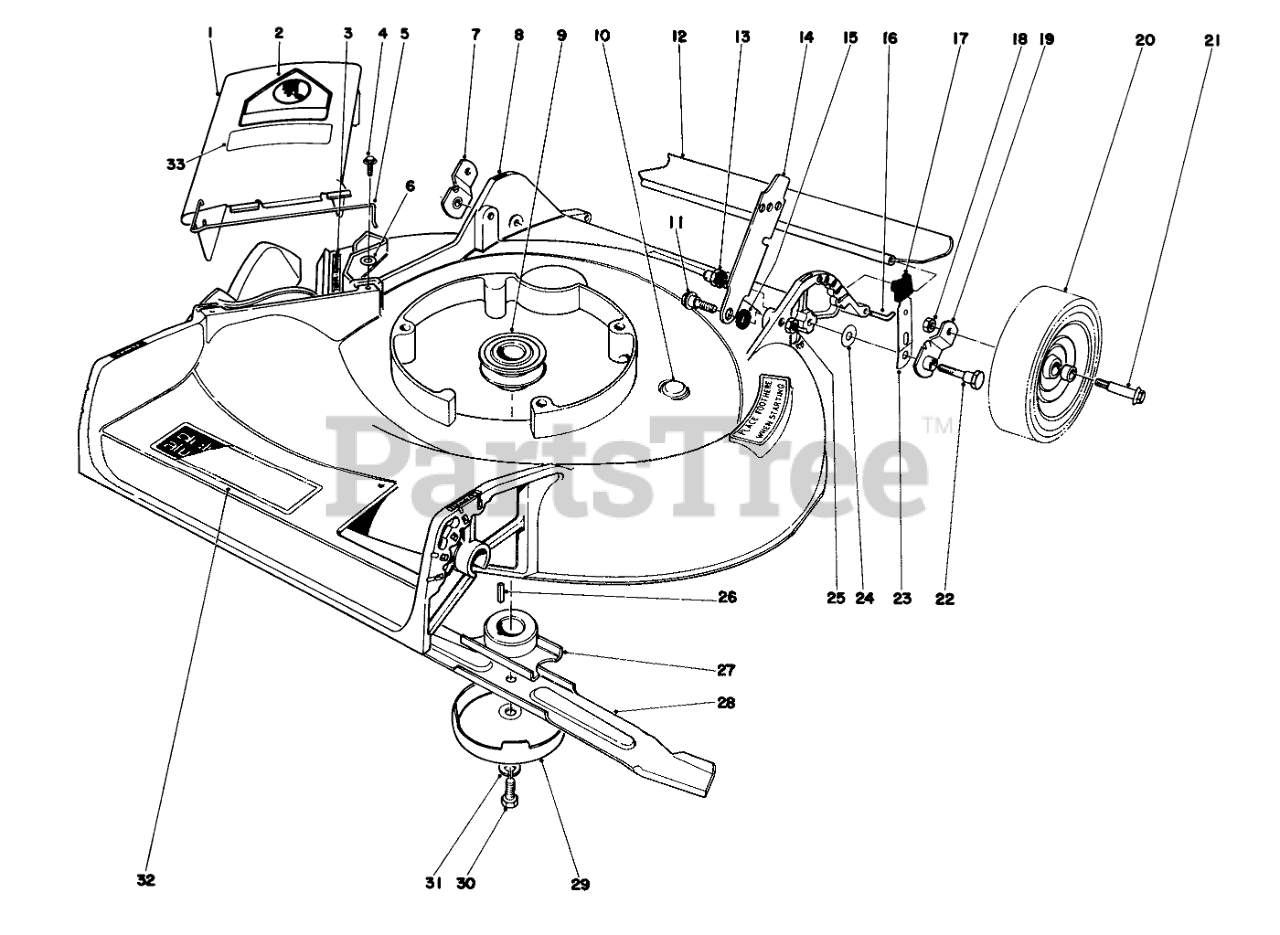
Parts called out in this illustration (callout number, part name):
1	Deflector Cover Assembly (Incl. Ref.#2,5&33)
2	DECAL-DANGER
3	Decal
4	SCREW
5	SPRING HINGE
6	WASHER-FLAT
7	Pivot Arm
8	Housing (Incl. Ref. #32)
9	DRIVER PULLEY
11	SCREW-SHOULDER
12	Rear Shield
13	HANDLE PIVOT NUT
14	Latch
15	HANDLE LATCH SPACER
16	SHIELD ROD
17	KNOB-ARM
18	Nut
19	Pivot Arm
20	Wheel & Tire Assembly
22	5/16-18 PIVOT SCREW
23	SPRING ARM ASM
24	Washer
25	Nut
26	KEY-SQUARE
27	Blade Retailer
28	Blade
29	AntiScalp Cup
30	SPECIAL SCREW
31	WASHER-LOCK
32	Decal-Deck
33	DECAL DEFLECTOR
